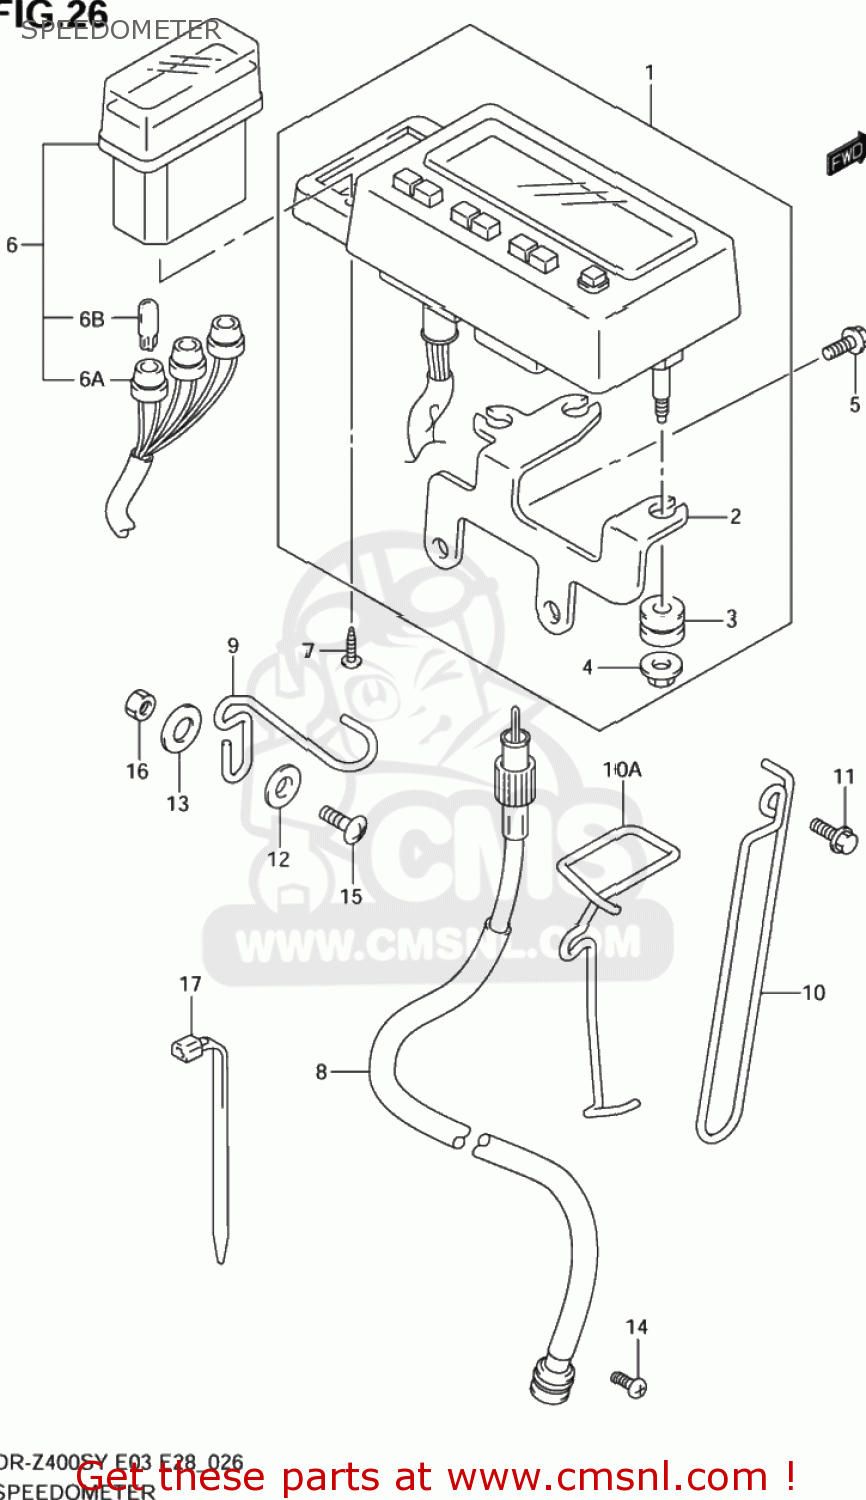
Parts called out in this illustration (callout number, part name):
1	SPEEDOMETER ASSY
2	BRACKET
3	CUSHION,METER
4	NUT
5	BOLT
6	BOX ASSY,PILOT LAMP
6A	SOCKET
6B	BULB(13.5V,2W,A7427)
7	SCREW
8	CABLE ASSY,SPEEDOMETER
9	GUIDE,SPEEDOMETER CABLE
10	GUIDE,METER CABLE NO.2
10A	GUIDE,SPEEDOMETER CABLE NO.3
11	BOLT(6X20)
12	WASHER(6.5X18X1.6)
13	WASHER
14	SCREW
15	SCREW
16	NUT 6MM
17	CLAMP(L:165)
